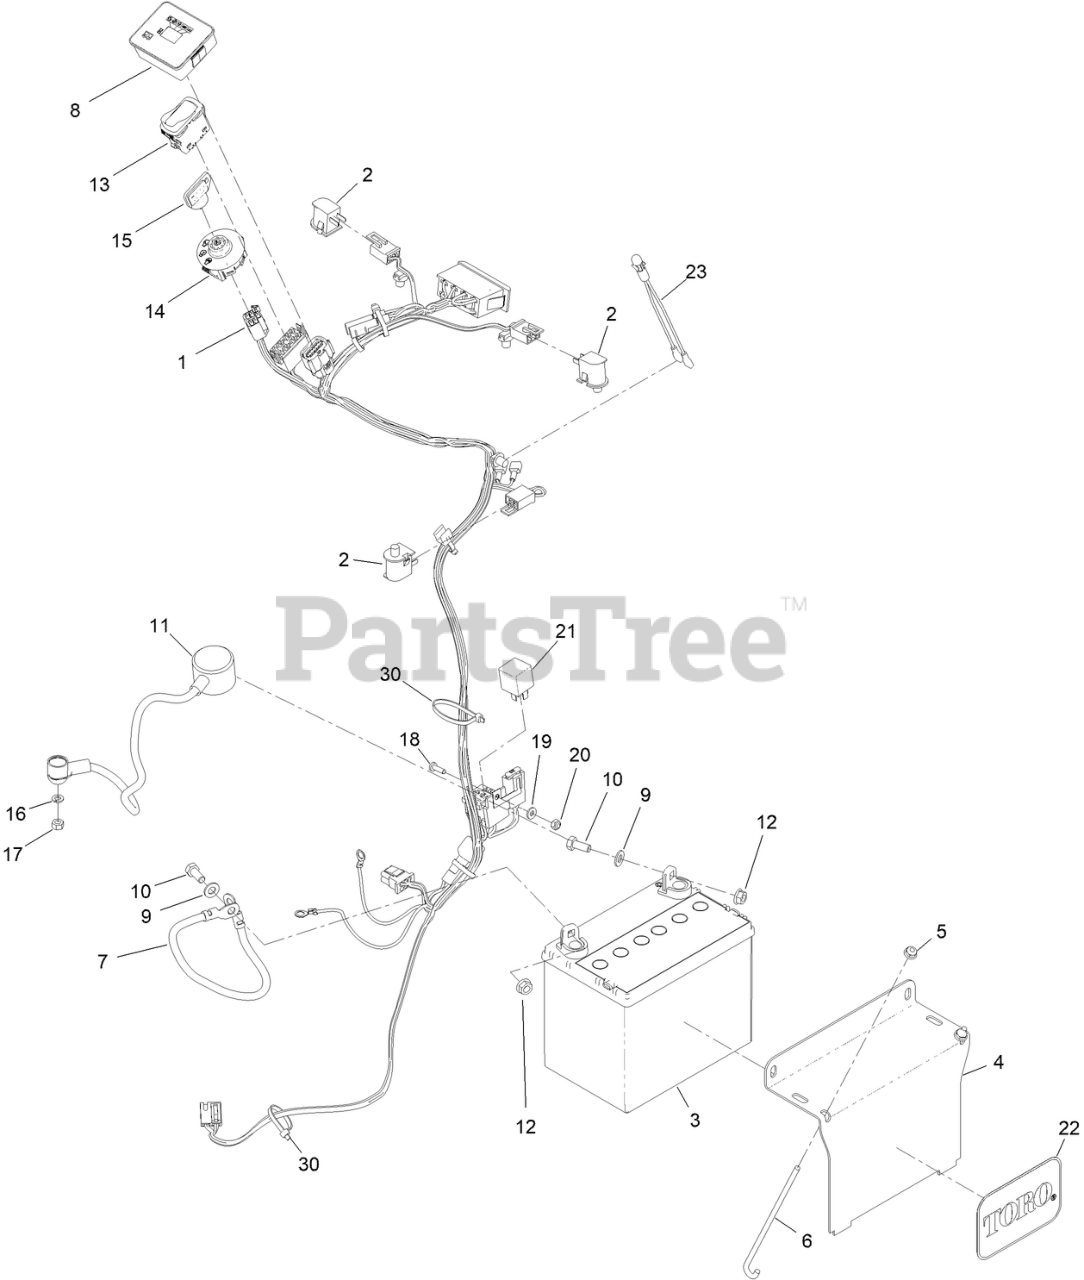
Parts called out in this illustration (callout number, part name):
1	HARNESS-WIRE, GRANDSTAND
2	SWITCH-BAIL
3	BATTERY-DRY
4	BRACKET-HOLD DOWN, BATTERY
5	NUT-HF
6	BOLT-HOLDDOWN
7	CABLE-BATTERY, BLACK
8	MODULE-METER, HOUR
9	WASHER-PLAIN
10	SCREW-HH
11	CABLE-BATTERY, POSITIVE
12	NUT-HHF, SMOOTH
13	SWITCH-ROCKER, (ON)-ON-OFF
14	SWITCH-IGNITION
15	KEY-IGNITION
16	WASHER-LOCK
17	NUT-HEX
18	SCREW-PPH
19	WASHER-FLAT
20	NUT-LOCK, NI
22	DECAL
23	INDICATOR-LED, RED
30	TIE-CABLE
